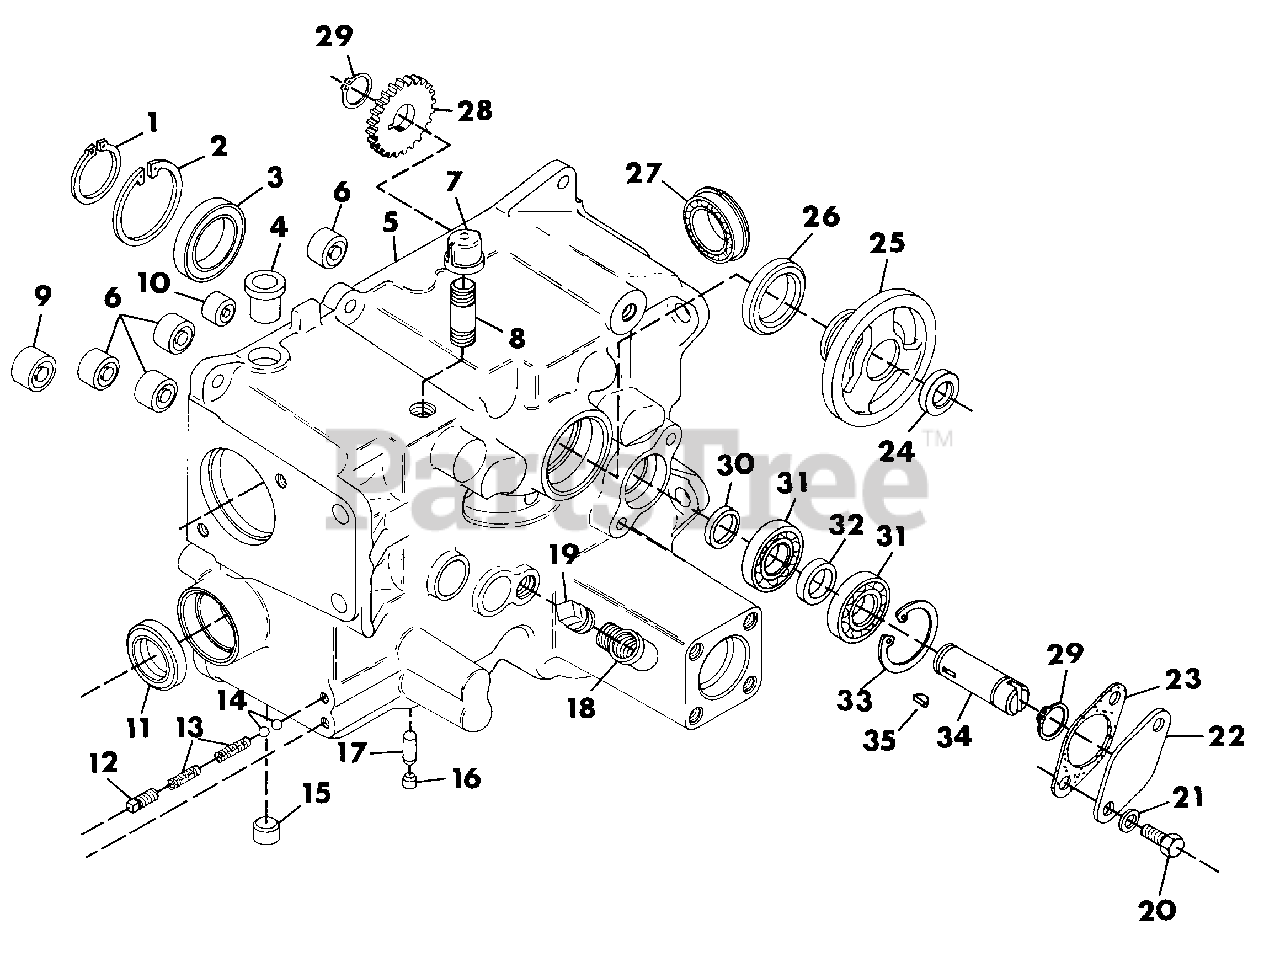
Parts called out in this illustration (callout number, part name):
1	RING, RETAINING 1.969 SHAFT
2	RING, RETAINING 3.156 BORE
3	BEARING, BALL 1.968X3.149X.629
4	BUSHING, .756X1.125X.75
5	CASE, TRANSMISSION
6	BEARING, NEEDLE .75X1.00X.75
7	CUP, PIPE 1/2 NPT
8	NIPPLE, PIPE 1/2X2.50
9	BEARING, NEEDLE 1.000X1.250X.750
10	BEARING, NEEDLE .625X.812X.750
11	SEAL, OIL 1.375X2.129X.312
12	PLUG, PIPE 1/8 SQ HD STEEL
13	SPRING, COMPRESSION 1.50X.30X26R
14	BALL, STEEL 5/16
15	PLUG
16	PLUG, CUP 3/8
17	PIN, INTERLOCK
18	E1, 1/2 90 STREET
19	PLUG, PIPE .5 SQ HD STEEL
20	BOLT, HEX 3/8-16X.75
21	WASHER, FLAT .406X.812X.065
22	PLATE, COVER
23	GASKET, COVER PLATE
24	SEAL, OIL .750X1.625X.250
25	HUB, CLUTCH
26	SEAL, OIL 2.250X3.005X.375
27	BEARING, BALL 1.378X2.440X.551
28	GEAR, HYDRAULIC PUMP
29	RING, RETAINING .594 SHAFT
30	SPACER, .620X.750X.276
31	BEARING, BALL .590X1.378X.433
32	SPACER, .620X.750X.364
33	RING, RETAINING 1.378 BORE
34	SHAFT, HYDRAULIC PUMP
35	KEY, WOODRUFF .125X.375 HARD
